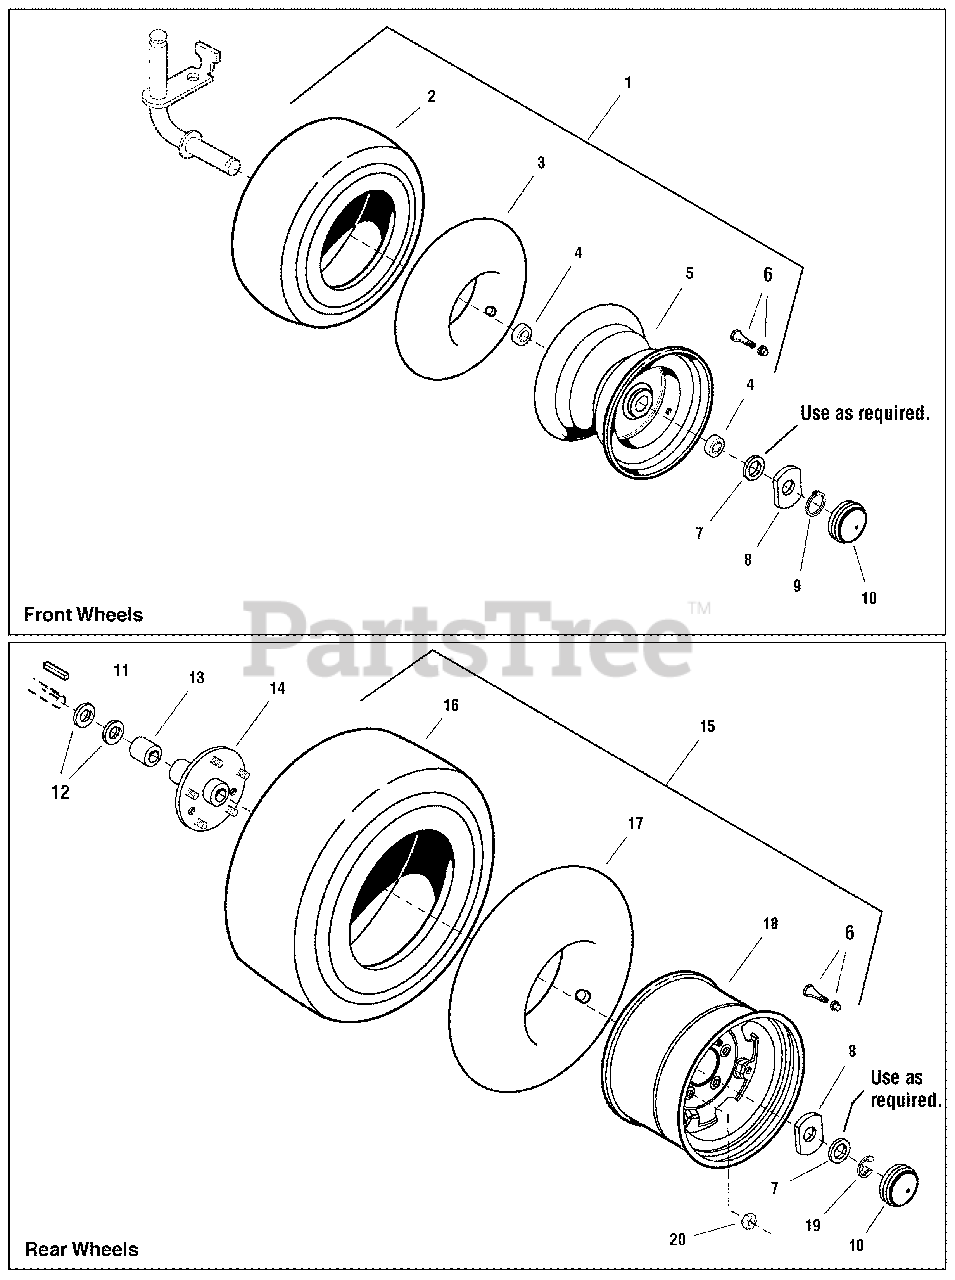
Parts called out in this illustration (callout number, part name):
1	WHEEL & TIRE ASSEMBLY, Front, (Includes Ref. Nos. 2, 3, 4, 5 & 6)
2	TIRE, 16 x 6-1/2 - 8 Super Turf, Front
3	TUBE, Tire 16 x 6-1/2 - 8, Front
4	BEARING, Ball
5	WHEEL, 5 3/8 x 7-15/16, Front
6	VALVE STEM & CAP ASSEMBLY
7	WASHER
8	WASHER, Special, 1 x 2-1/2
9	RING, Shaft
10	CAP, Hub Grey, 2-23/64
11	KEY, HI PRO, 1/4 x 2
12	WASHER
13	SPACER, 1-1/16 x 1-1/2 x 1-23/32, Black
14	PLATE & HUB ASSEMBLY, Rear Wheel w/Studs
15	WHEEL & TIRE ASSEMBLY, Rear 23" (Includes Ref. Nos. 6, 16, 17 & 18)
16	TIRE, 23 x 10-1/2 - 12 Super Turf, Rear
17	TUBE, Tire 23 x 10-1/2 - 12, Rear
18	WHEEL, 7 x 12, Rear
19	RING, Shaft
20	NUT, Hex 7/16-20, For Wheel Bolt
